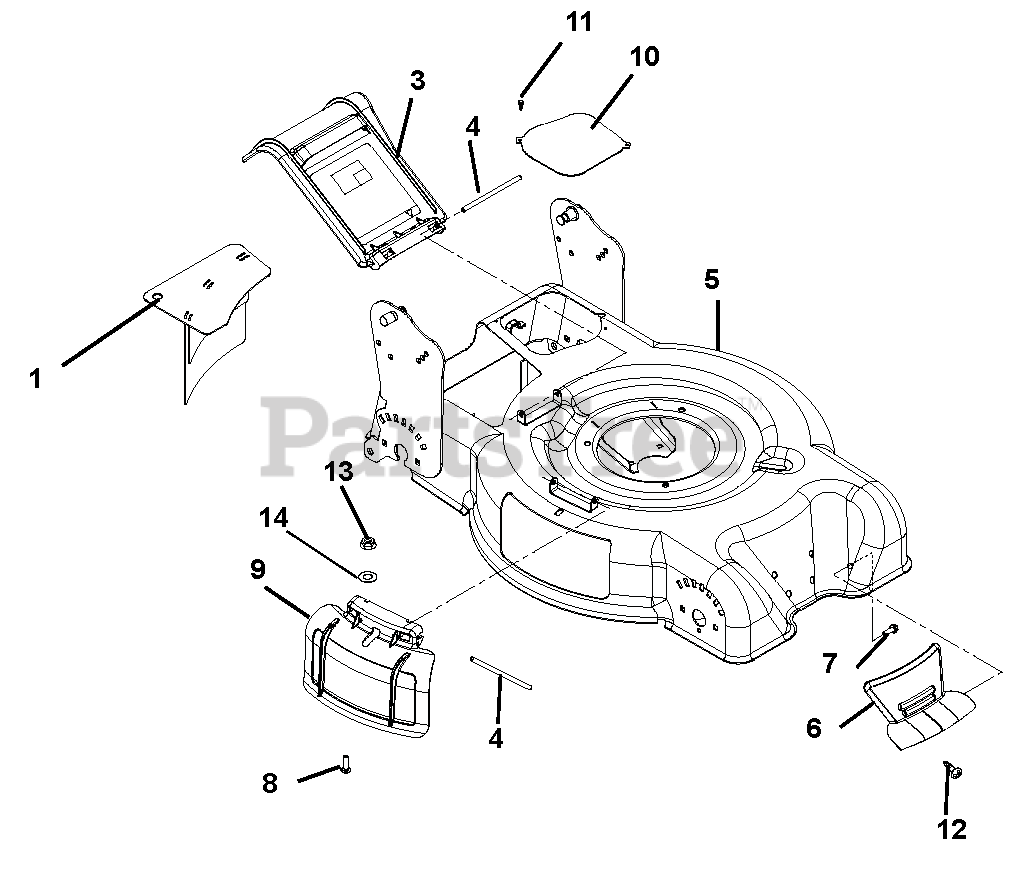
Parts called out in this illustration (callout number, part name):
1	PLUG, MULCH (STEEL)
2	BAGGER DOOR
3	REAR DISCHARGE COVER
4	PIN, HINGE
5	21" DECK WELDMENT
6	GRILL INSERT
7	SCR-TAP 12-12X.75 HI-LOW YZ
8	@BLT-RDHDSQNK .31-18X.75 G5YZ
9	MULCH COVER
10	COVER, TRANSMISSION ACCESS
11	@SCR-TAP 10-24X.375 HWH YZ TR
12	SCREW, SELF DRILL/TAP
13	@NUT-LK-TOP-FLG .31-18 YWZC
14	@WSHR-FL-STL.406X.812X.065 YWZ
